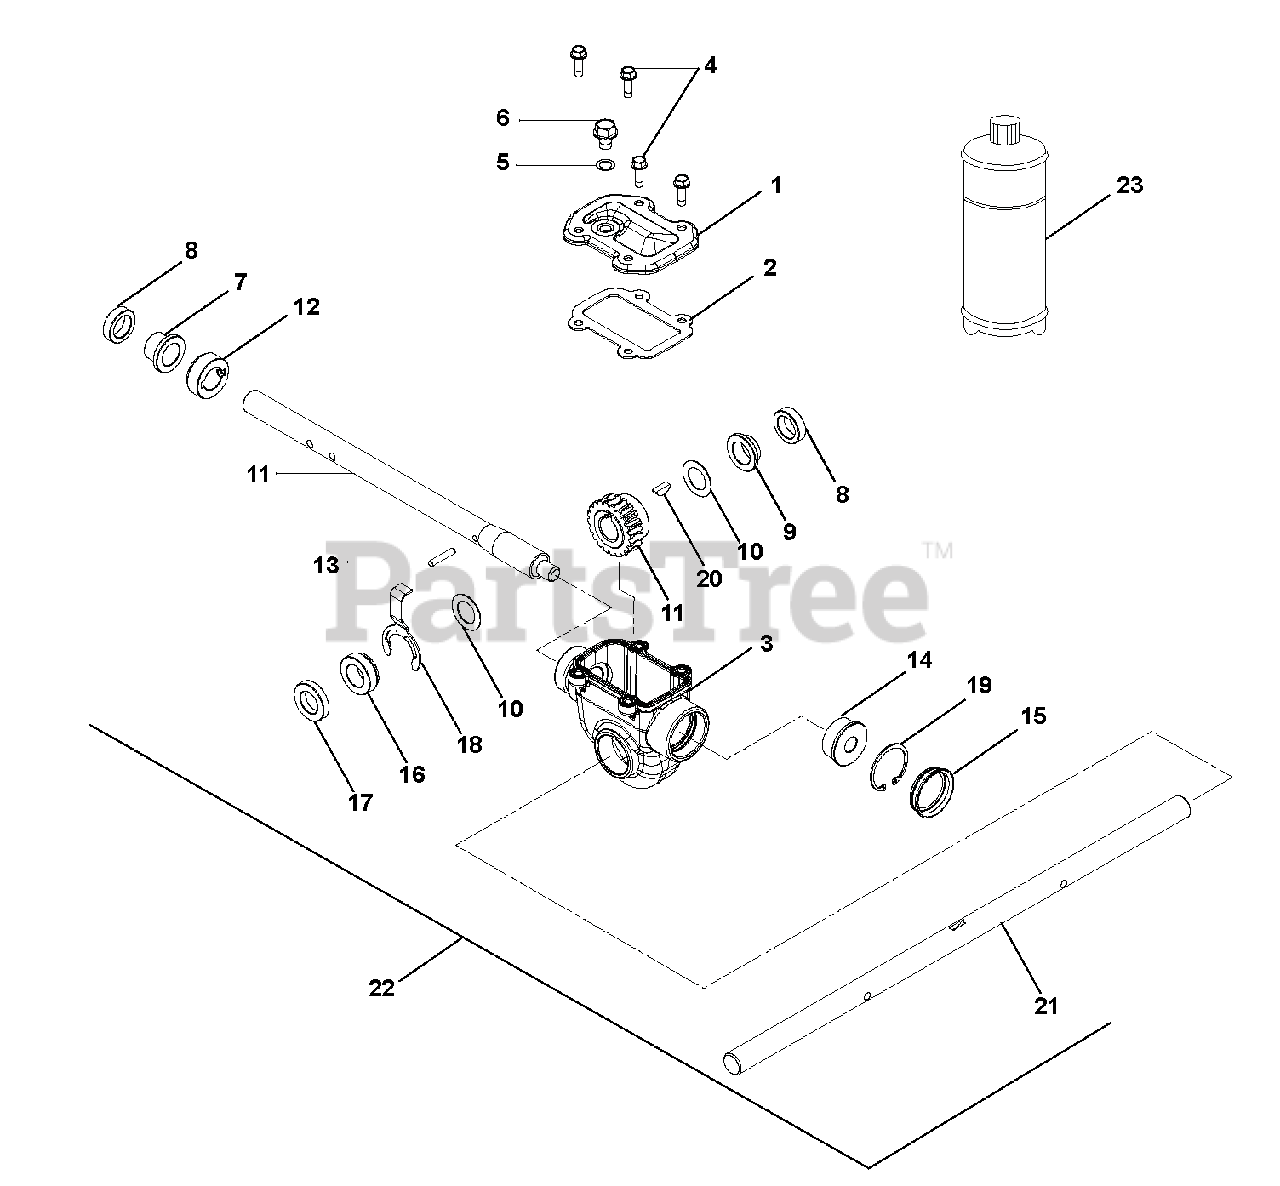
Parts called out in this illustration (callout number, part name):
1	COVER, TOP - COMPACT
2	GASKET, TOP - COMPACT GEARCASE
3	GEARCASE, COMPACT ALUMINUM
4	SCR-TAP .25-20X.75 HWH TR YWZ
5	WSHR-BND-SEAL .38X.75X.11 GALV
6	@SCR-ROLOK .38-16X.50 HWH YWZC
7	BSHG-FLG .755X.878X.75X1.25
8	SEAL-OIL .748X1.125X.312 TB2-H
9	BSHG-FLG .755X.878X.424X1.25
10	WSHR-FL-STL .760X1.225X.032 YZ
11	SHAFT AND WORM GEAR ASSEMBLY
12	THRUST COLLAR, .75" ID SLIPFIT
13	PIN-STR .188X1.00 6150
14	BSHG-FLG .503X1.303X.62X1.465
15	COVER, GEAR CASE 1.50"
16	BSHG-FLG COMPACT, RIGHT
17	SEAL-OIL .748X1.300X.250 TB2-H
18	BUSHING RETAINER, COMPACT
19	RG-RTNG-INT 1.500X.050
20	KEY-WDRF .19X.63 HRD #61
21	SHAFT, RAKE - 20" (.750 DIA)
22	GEAR CASE, 20" ALUM SM TOP-LD
23	ARIENS L3 LUBE, 8 OZ BOTTLE
